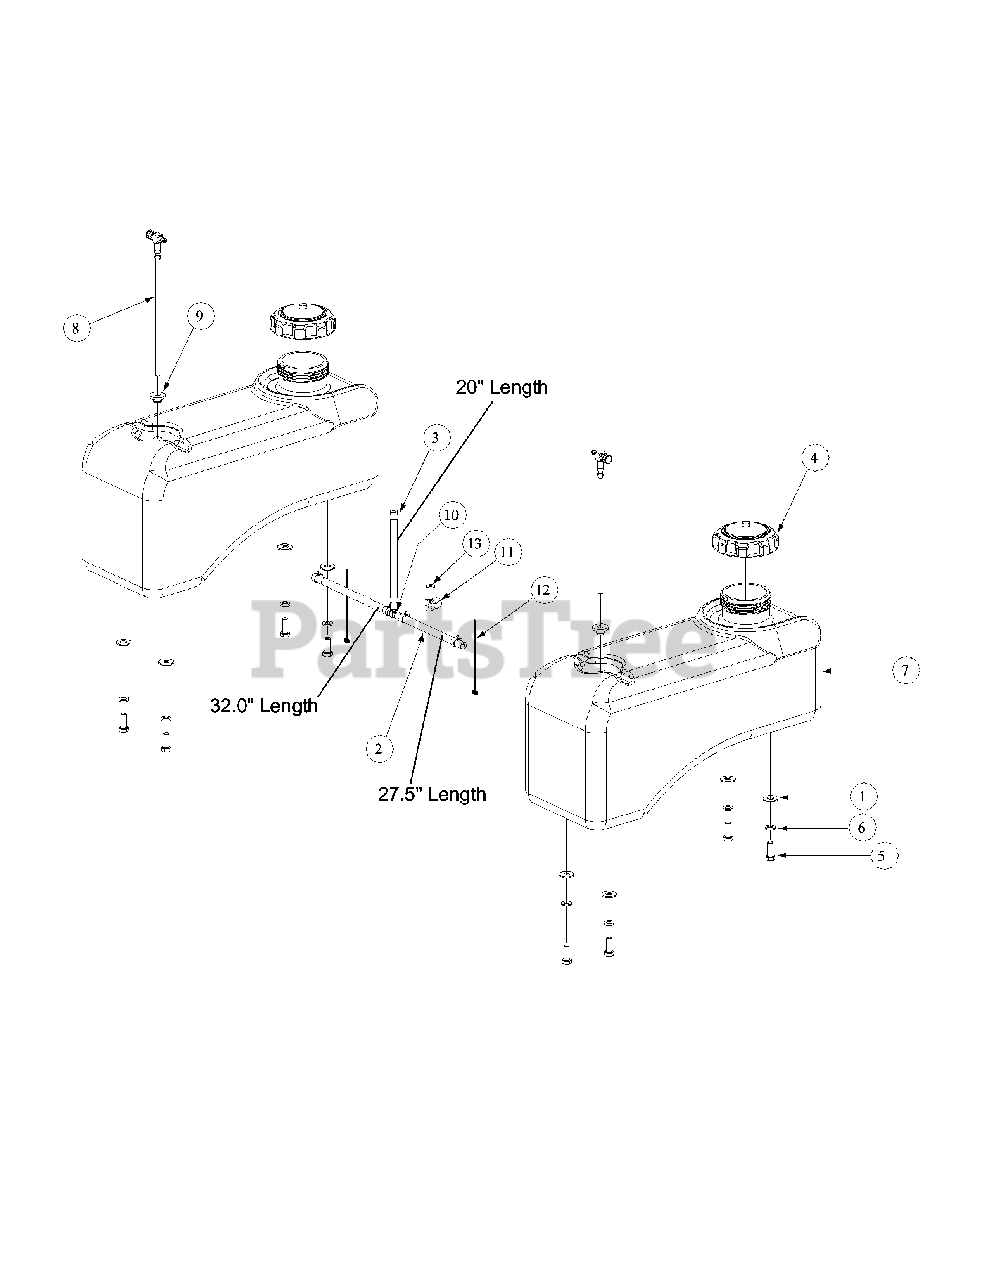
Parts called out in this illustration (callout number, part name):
1	Flat Washer, .406 ID, 1.0 OD, .105
2	Hose, 1/4" Fuel Line
3	Clamp, Union
4	Fuel Cap, 3.5
5	Hex, Cap Screw, 3/8-16, .88
6	Lock Washer, 3/8
7	Fuel Tank
8	Fuel Fitting
9	Fuel Tank Grommet
10	Tee Fitting, Fuel
12	Cable Tie
13	Flatwasher 1/4 x .630 x .0515
